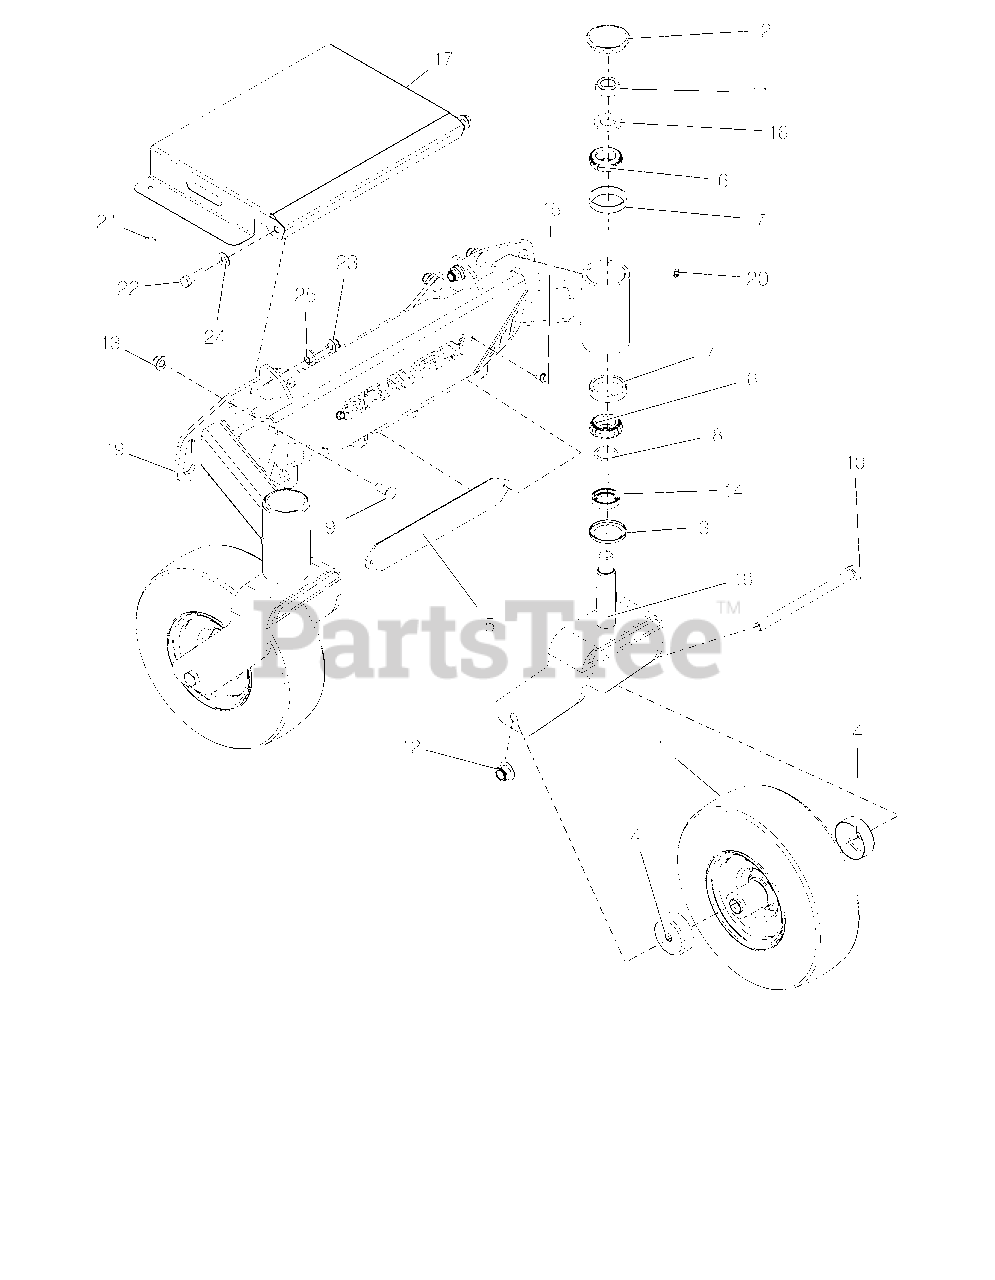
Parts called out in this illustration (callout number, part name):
1	ASM, WHL/TIRE 11X4.00-5
2	CAP, DUST
3	BEARING SEAL 1.5 X 2 X .18
4	SHIELD, WHEEL BEARING
5	BACK, NAMEPLATE
6	BRG-CONE 1.0X.58
7	BRG-CUP1.980X.420
8	O-RING 1.000X1.250X
9	@BLT-RDHDSQNK .38-16X1.00 G5YZ
10	@BLT-HEX .50-13X7.00 GR5 YWZC
11	NUT-JAM TOPLK .75-16 YWZC
12	@NUT-LK-NYL-FLG .50-13 YWZC
13	@NUT-LK-NYL-FLG .38-16 YWZC
14	SPCR, CASTER FORK (1.00)
15	SCR-TAP .25-20X.50 HWH TR YWZ
16	@WSHR-FL-STL.812X1.50X.135YWZC
17	SHIELD, HEAT
18	WLDMT, FRONT FORK
19	WLDMT, FRONT AXLE
20	FTG, .25-28 FLUSH MNT GREASE
21	BUMPER GROMMET
22	@BLT-HEX .38-16X1.25 GR5 YWZC
23	@NUT-LK-NYL-FLG .38-16 YWZC
24	@WSHR-FL-STL.406X.812X.065 YWZ
25	BSHG-FLG .32X.500X.344X.880
